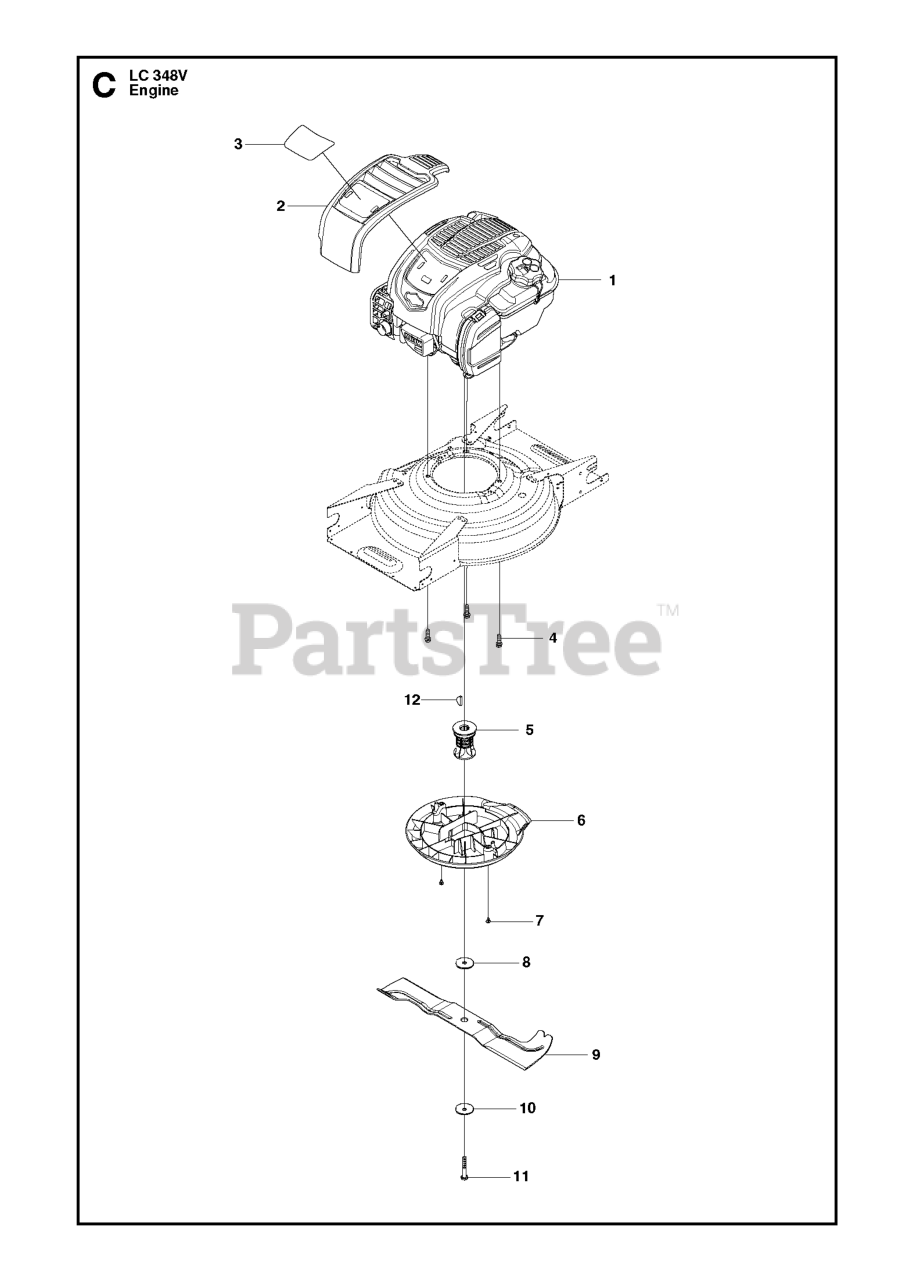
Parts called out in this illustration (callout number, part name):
4	BOLT 3/8-16X1-1/8
6	BELT COVER A009-2
10	SPRINGS
